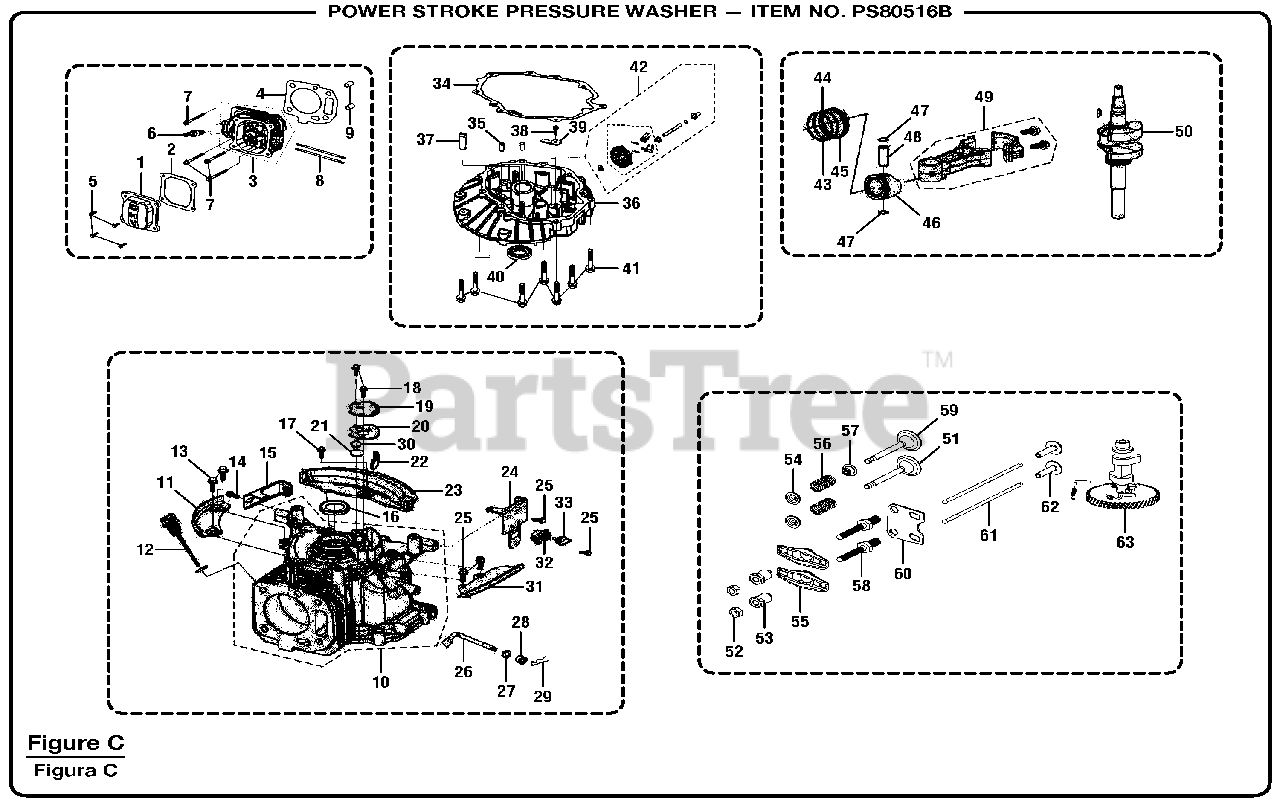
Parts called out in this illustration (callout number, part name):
1	Cylinder Head Cover
2	Cylinder Head Cover Gasket
3	Cylinder Head Assembly
4	Cylinder Head Gasket
7	Cylinder Head Bolt
10	Crankcase Assembly
11	Crankcase Side Shield
12	Oil Dipstick Assembly
15	Fuel Tank Right Bracket
19	Breath Groove Cover Plate
20	Breath Groove Gasket
22	Breath Groove Strainer
23	Crankcase Rear Shield
24	Fuel Tank Left Bracket
30	Breath Piece Return Spring
31	Crankcase Right Shield
32	Fuel Valve Holder
34	Crankcase Gasket
36	Crankcase Cover
37	Returning Oil Block
39	Governor Spindle Compression Plate
42	Governor Gear Assembly
44	The Second Ring
47	Piston Pin Clip
50	Crankshaft Assembly
54	Spring Seat
58	Valve Adjusting Bolt
60	Lifter Stop Plate Assembly
63	Camshaft Assembly
